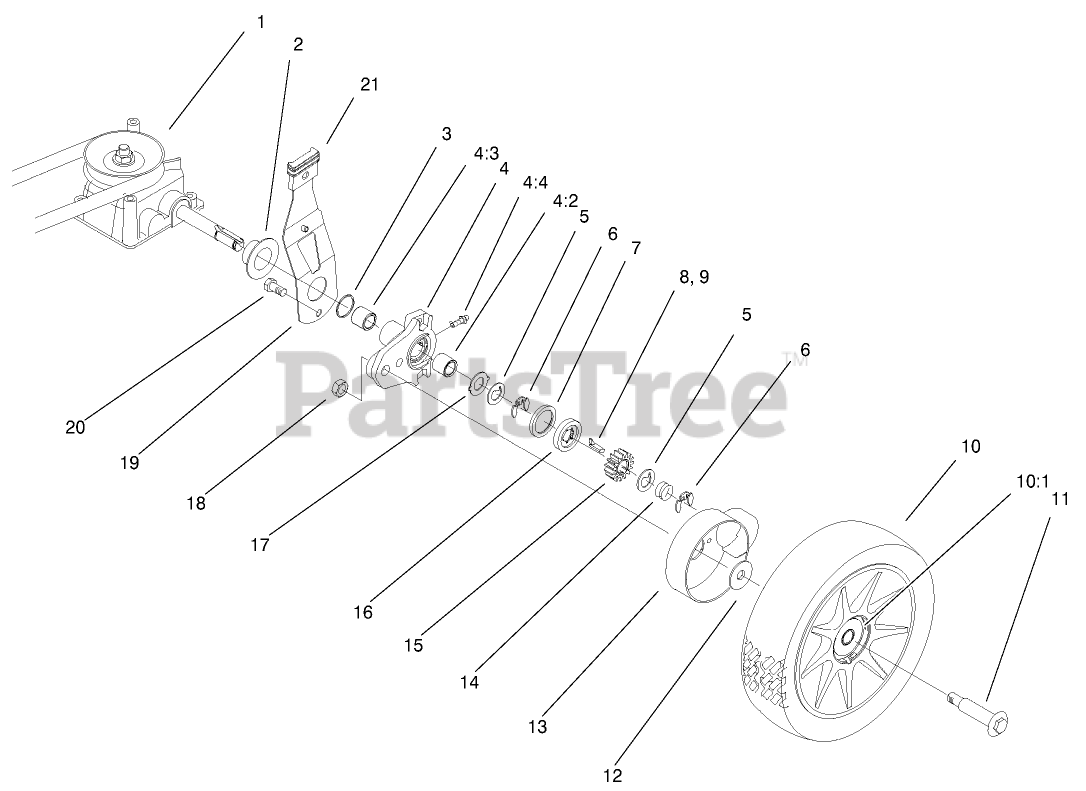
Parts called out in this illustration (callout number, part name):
1	V-BELT
2	CAP-END
3	O-RING
4	PIVOT ARM ASM
4:2	BUSHING
4:3	BUSHING
4:4	FITTING-GREASE
5	WASHER-THRUST, KEYED
6	RING-RETAINING,CLIP
7	RING-FRICTION
8	KEY-ROCKING, RH
9	KEY-ROCKING, LH
10	WHEEL TIRE ASM (SP)
10:1	BUSHING
11	BOLT-SHOULDER
12	SPACER-COVER, WHEEL
13	COVER-WHEEL
14	SPRING-COMPRESSION
15	GEAR-PINION
16	WASHER-CLUTCH
17	WASHER-ARM, PIVOT
18	LOCKNUT
19	SPRING ARM ASM
20	SCREW-HWH
21	KNOB-ARM
